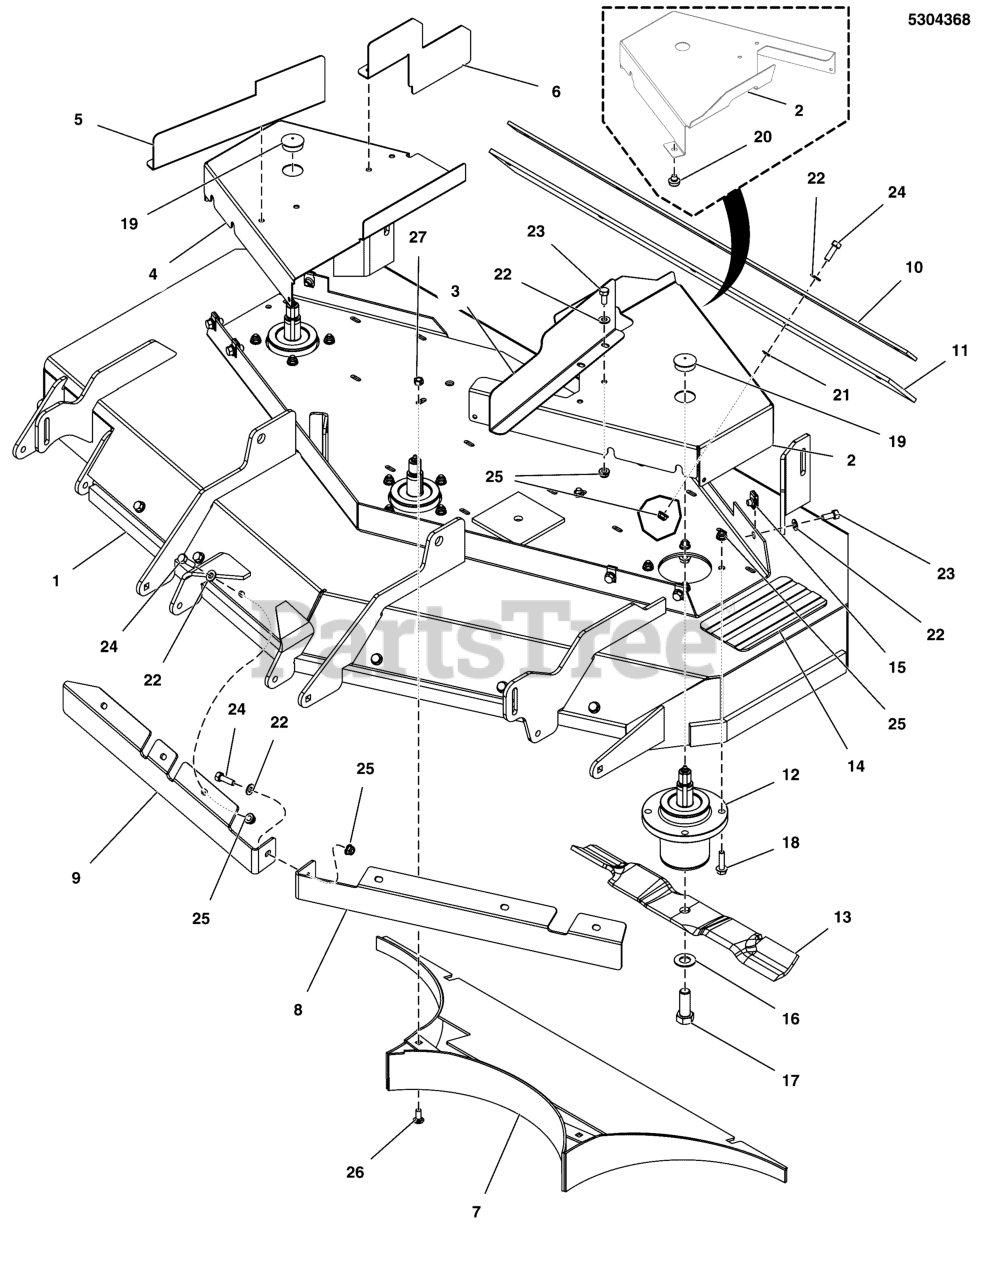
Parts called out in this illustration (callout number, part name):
1	DECK SHELL W/DECALS,52RDCE,2100,5414779B
2	PLATE, DECK GUARD, 52, LH - RED
3	PLATE, DECK SHIELD, FRONT, 52, LH - RED
4	PLATE, DECK GUARD, 52, RH - RED
5	PLATE, DECK SHIELD, FRONT, 52, RH - RED
6	PLATE, DECK SHIELD, REAR, 52, RH - RED
7	WELD, REAR BAFFLE, SHRT - BLK
8	BAFFLE, FRONT DISCHARGE LH - RED
9	BAFFLE, FRONT DISCHARGE RH - RED
10	PLATE, FLAP RETAINER, 2000 RD - BLK
11	FLAP, 2000 REAR DISCHARGE
12	SPINDLE, ASSM, ALUMINUM - 5.25
13	BLADE SET, MULCH, 52 DECK
14	SAFETY WALK, 4.00 X 7.50
15	BODY CLIP, 5/16-18-7GA MATERIAL
16	WASHER, BLADE BOLT, 9/16" F436, CZ
17	BOLT, 5/8-11 X 1-3/4 GD8
18	BOLT, 5/16-18 X 1 1/4 FLANGE
19	PLUG, PANEL, 1.25 - BLACK
20	MNT, VBRTN, RBBR
21	5/16 PUSH-ON NUT RETAINER, STL, CZ
22	WASHER, 5/16" SAE
23	BOLT, 5/16-18 X 3/4 GD5
24	BOLT, 5/16-18 X 1 GD5 CZ
25	NUT, 5/16-18 HEX NYLOCK FLANGE
26	BOLT, 5/16-18 X 3/4, CARRIAGE
27	NUT, 5/16-18, HEX, CNTR LK,ZINC PHOS/OIL
